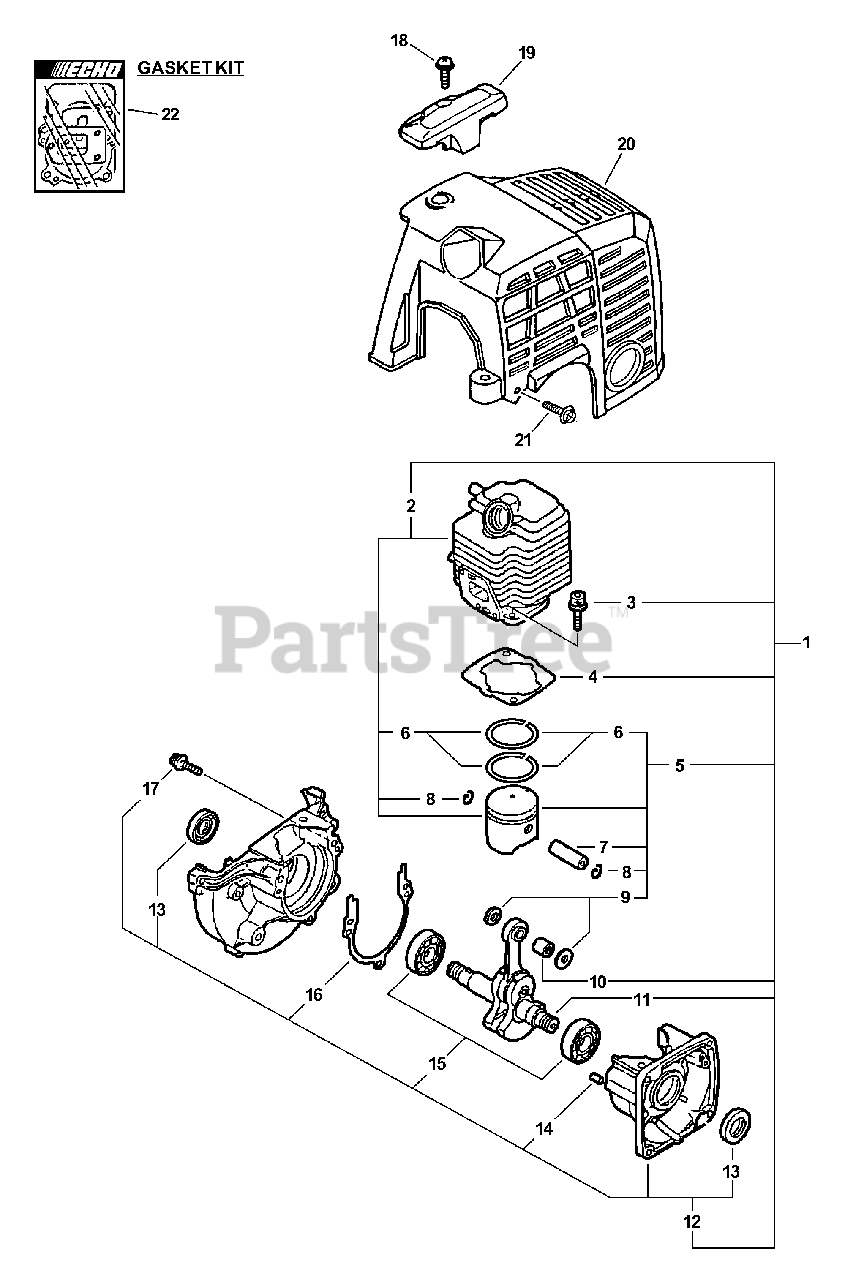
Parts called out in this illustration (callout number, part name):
1	SHORT BLOCK ES-2400
2	CYLINDER/PISTON KIT
3	BOLT 5×22
4	GASKET, CYLINDER
5	PISTON KIT
6	RING, PISTON
7	PIN, PISTON 8
8	RING, SNAP
9	WASHER, THRUST
10	BEARING, NEEDLE
11	CRANKSHAFT ASSY
12	CRANKCASE KIT
13	SEAL, OIL 12
14	PIN, LOCATING 4
15	BEARING, BALL - 6201 C3
16	GASKET, CRANKCASE
17	BOLT 5×28
18	SCREW 5×16
19	GUARD, TOP
20	COVER, ENGINE
21	BOLT 4×16
22	GASKET KIT
